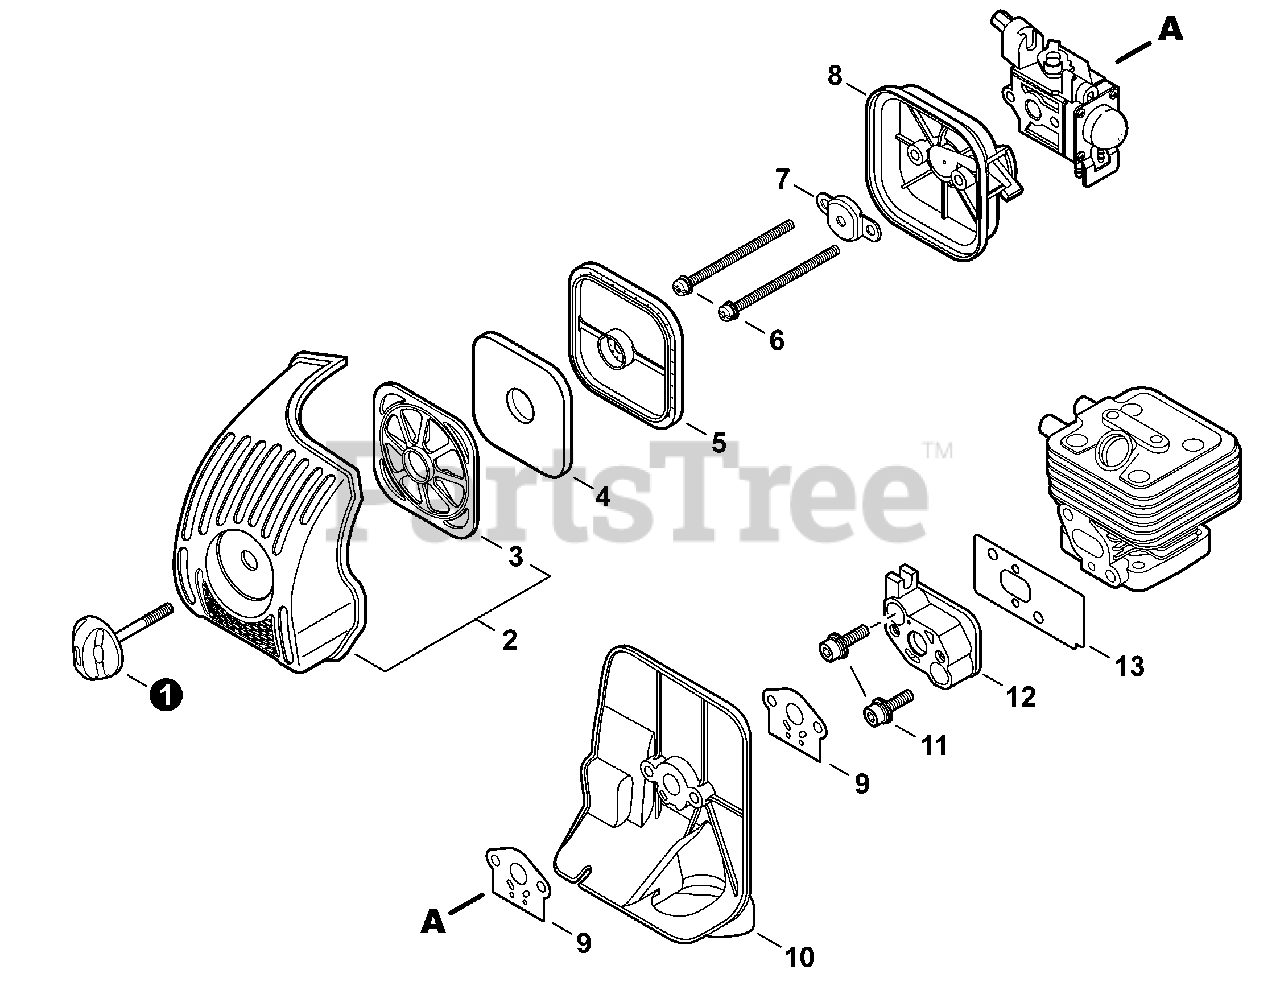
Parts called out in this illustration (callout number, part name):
1	THUMBSCREW
2	COVER KIT, AIR FILTER
3	RETAINER, PRE-FILTER
4	PRE-FILTER, FOAM
5	FILTER, AIR - DOUBLE LAYER
6	SCREW 5x70
7	PLATE, PREVENT
8	CASE, AIR FILTER
9	GASKET, INTAKE
10	PLATE, INSULATOR
11	BOLT 5x25
12	INSULATOR, INTAKE
13	HEAT SHIELD, INTAKE
